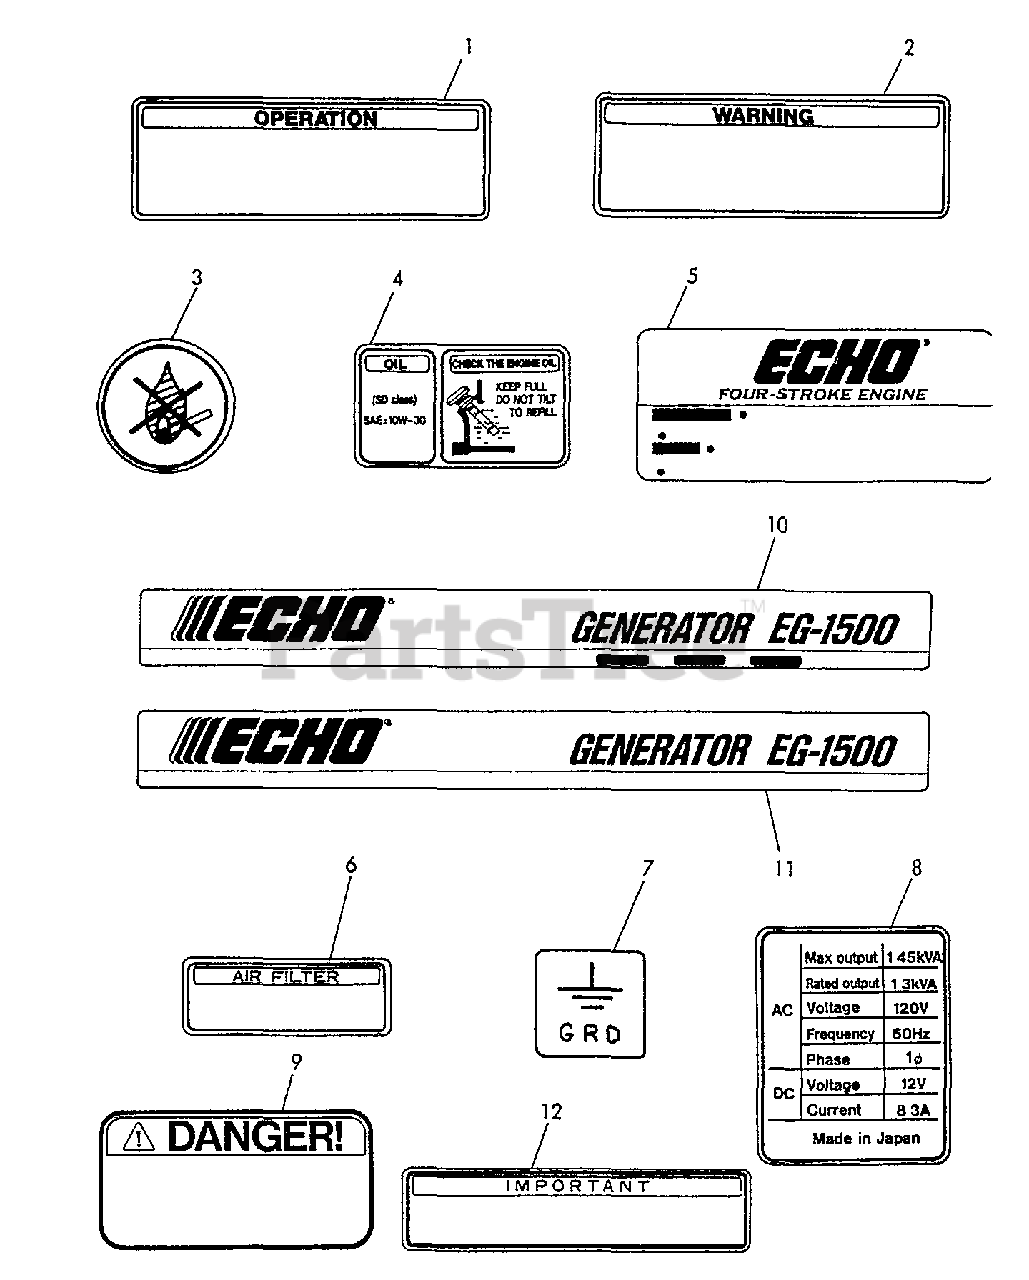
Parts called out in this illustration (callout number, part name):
1	LABEL
2	LABEL - WARNING
3	LABEL, NON FIRE
4	LABEL, OIL
5	LABEL, ECHO
6	LABEL - AIR FILTER
7	LABEL, EARTH
8	LABEL - GENERATOR
9	LABEL DANGER
10	LABEL - GENERATOR
11	LABEL - GENERATOR
12	LABEL - IMPORTANT
